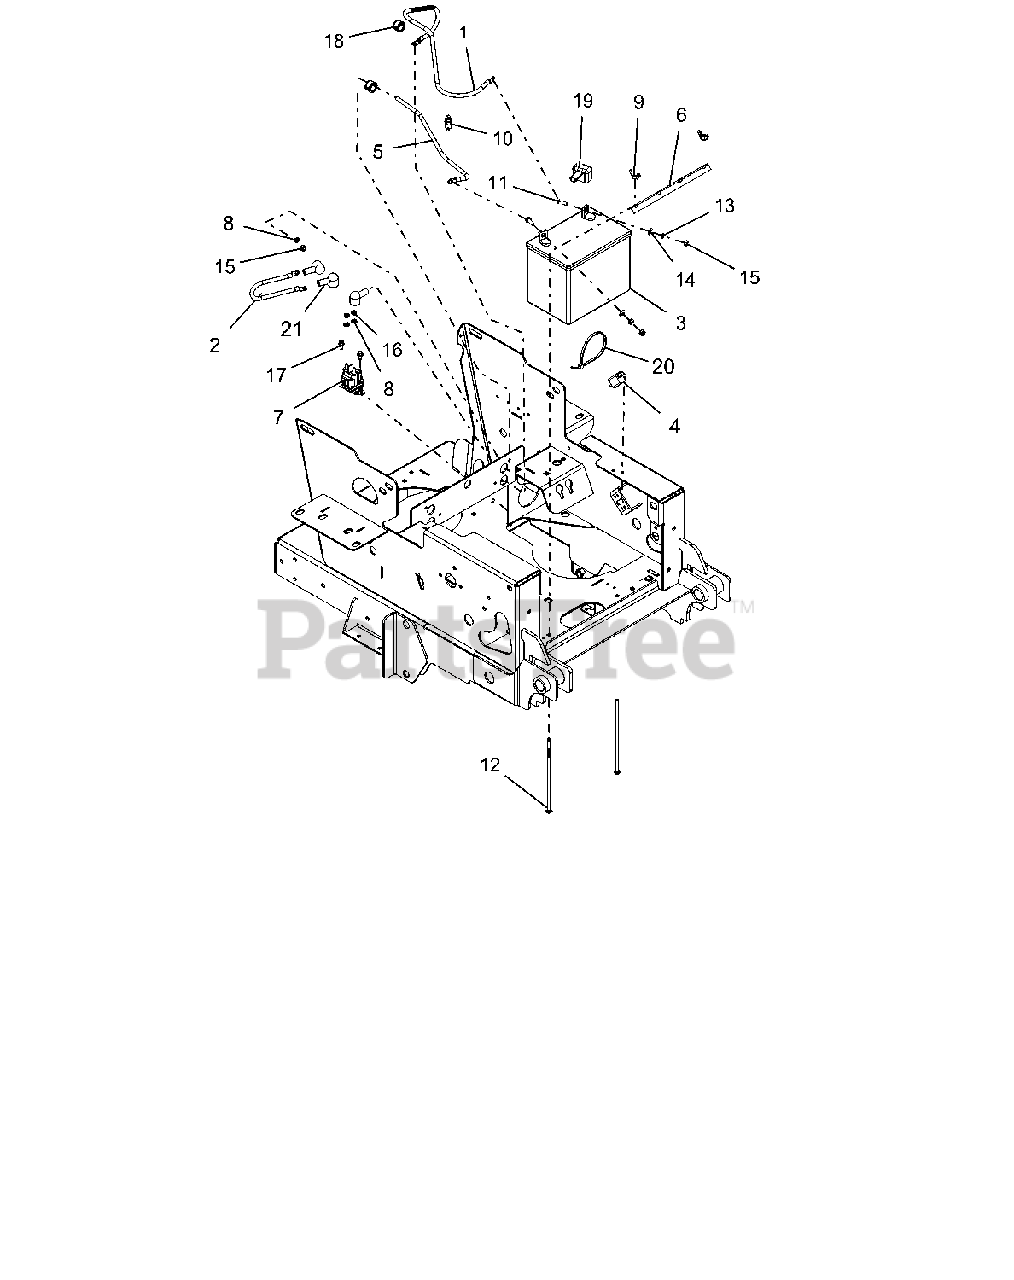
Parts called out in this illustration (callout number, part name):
1	CABLE,POS W/(2)1/4 RING 21.5LG
2	CABLE, POS W/(2)1/4 RING 9.0LG
3	BATTERY, 300 CCA 10U1L
4	SWITCH, SINGLE POLE N.O.
5	CABLE-NEGATIVE BATTERY 24.00"
6	HOLD DOWN
7	SOLENOID, STARTER (SEALED)
8	@WSHR-LK-EXT.262X.502X.026YWZC
9	NUT-LK WING .250-20 YWZC
10	CLIP,T,.31-.38,
11	@BLT-HEX .25-20X.75 GR5 YWZC
12	BLT-RDHDSQNK .25-20X7.50 GR2YZ
13	@WSHR-LK .25X.062 REG YWZC
14	@WSHR-FL-STL.281X.62X.065 YWZC
15	@NUT-HEX .25-20 YWZC
16	NUT-HEX M6X1.0 YWZC
17	SCR-TAP .25-20X.50 HWH TR YWZ
18	BUSH, PANEL SNAP .687X.875X.56
19	INSULATOR
20	CABLE TIE LG 5-1/2
21	BOOT, EYELET TERMINAL
